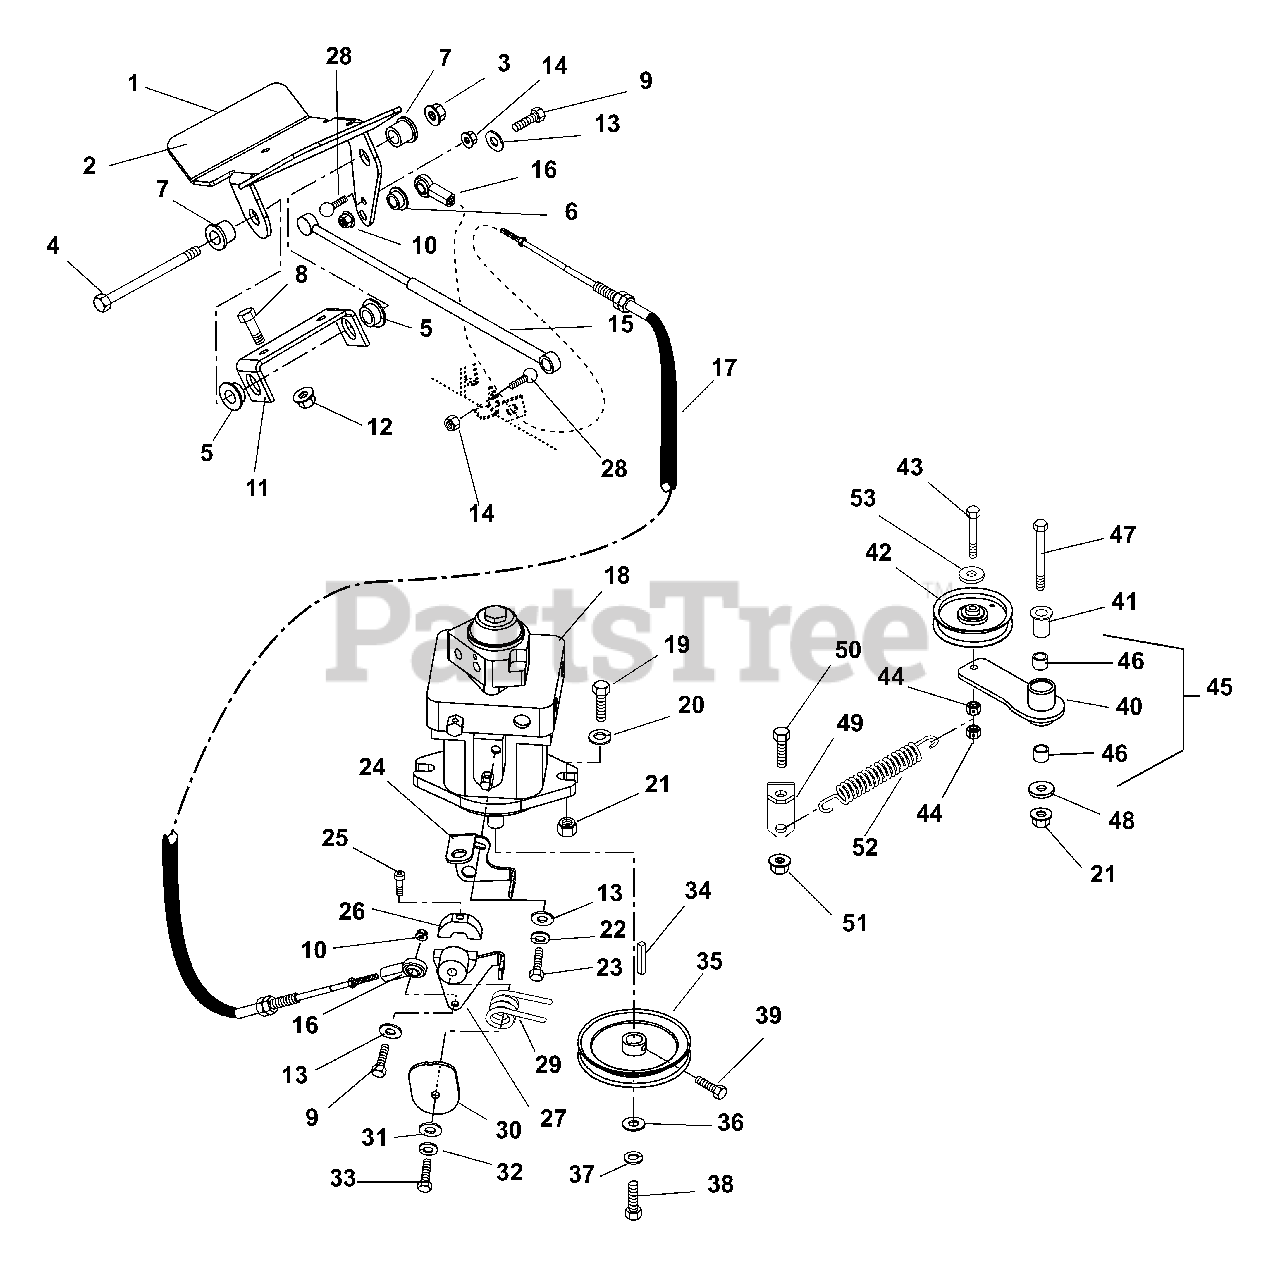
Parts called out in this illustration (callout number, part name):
1	Pedal, Direction Control
2	Pad, Foot Clutch Pedal
3	Nut-Locking-Top-Flange .50-13
4	Bolt-Hex .50-13 x 6.50 Grade 5
5	Bushing, Flange-Nylon .762 x 1.00 x .58 x 1.48
6	Bushing-Flange .265 x .437 x .250 x .750
7	Bushing, Flange-Nylon .515 x .75 x .745 x 1.00
8	Bolt, Hex .38-16 x 1.00 Grade 5
9	Bolt-Hex .25-20 x 1.00 Grade 5
10	Nut-Locking-Top-Flange .25-20
11	Bracket, Control Pedal
12	Nut-Locking-Top-Flange .38-16
13	Washer-Flat-Steel .28 x .62 x .065
14	Nut-Locking-Top-Flange .31-18
15	Dampener Control
16	Rod End, Female .25-28
17	Cable, Forward-Reverse Control
18	Pump
19	Bolt-Hex .50-13 x 1.50 Grade 5
20	Washer-Flat-Steel .531 x 1.06 x .095
21	Nut-Locking-Top-Flange .50-13
22	Washer-Locking-External .262 x .502 x .026
23	Bolt-Hex .25-20 x .75 Grade 5
24	Arm, Neutral Return
25	Screw-Socket Head M6 x 1.00 x 35mm
26	Hub, Pump Neutral
27	Weldment, Pump Neutral
28	Stud, Ball
29	Spring-Torsion .156 x 1.275 x .77
30	Cam, Neutral Switch
31	Washer-Flat-Steel .344 x .688 x .065
32	Washer-Locking .31 x .078 Regular
33	Bolt-Hex .31-24 x .75 Grade 5
34	Key-Straight 5mm x 5mm x 30mm
35	Sheave, Pump
36	Washer-Flat-Steel .281 x 1.000 x .063
37	Washer-Locking .25 x .062 Regular
38	Bolt-Hex M6 x 1.0 x 12
39	Bolt-Hex .25-20 x .50 Grade 5
40	Arm, Idler Pivot
41	Bearing, Pedestal
42	Idler-V 4.00 x .38
43	Bolt-Hex .38-16 x 2.25 Grade 5
44	Nut-Locking-Center .38-16
45	Asm, Idler Pivot Arm (Contains Items 40 and 46)
46	Bearing, 1.00 x 1.12 x .75
47	Bolt-Hex .50-13 x 4.00 Grade 5
48	Washer-Flat Steel .53 x 1.25 x .100
49	Anchor, Spring Idler
50	Bolt-Hex .38-16 x 1.00 Grade 5
51	Nut-Locking-Top-Flange .38-16
52	Spring, Extension
53	Washer-Flat-Steel .406 x .812 x .065
